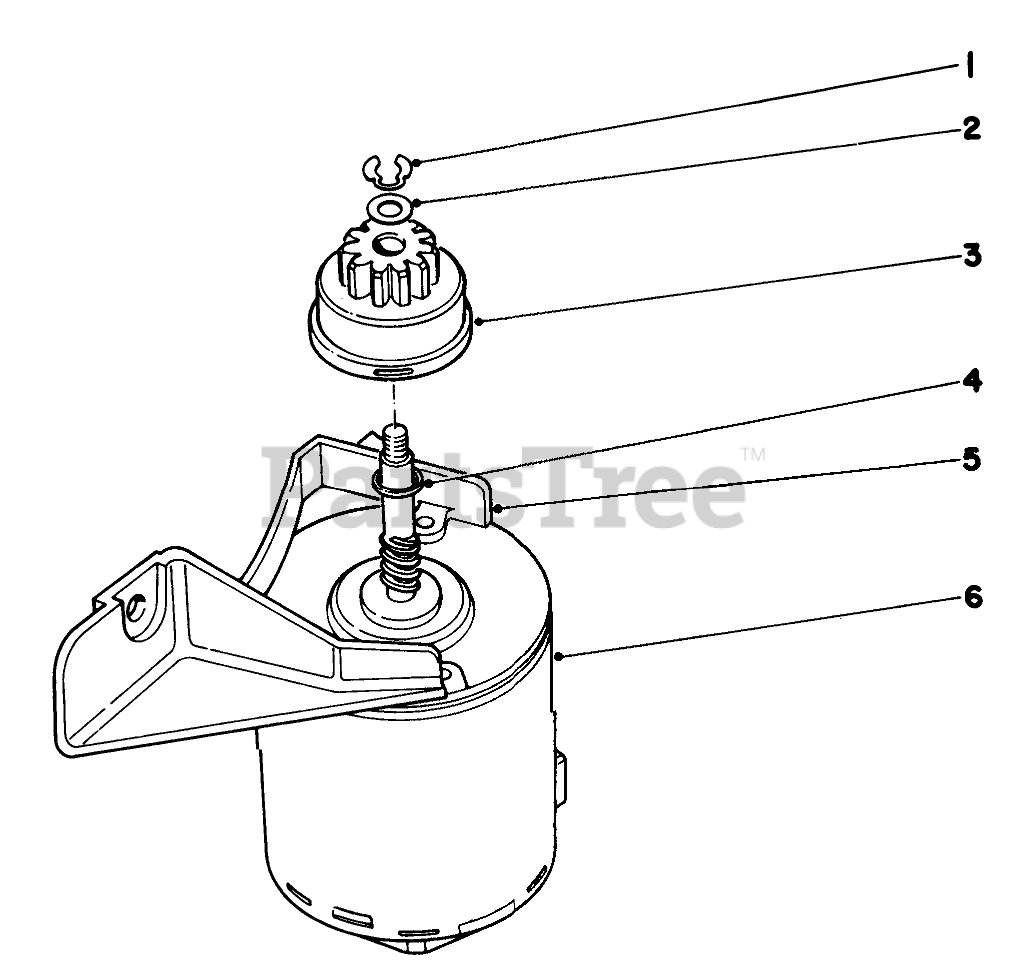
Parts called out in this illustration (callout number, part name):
1	RING-RETAINING
2	WASHER
3	PINION ASM
4	Spacer
5	Mounting Bracket
6	Starter Motor
